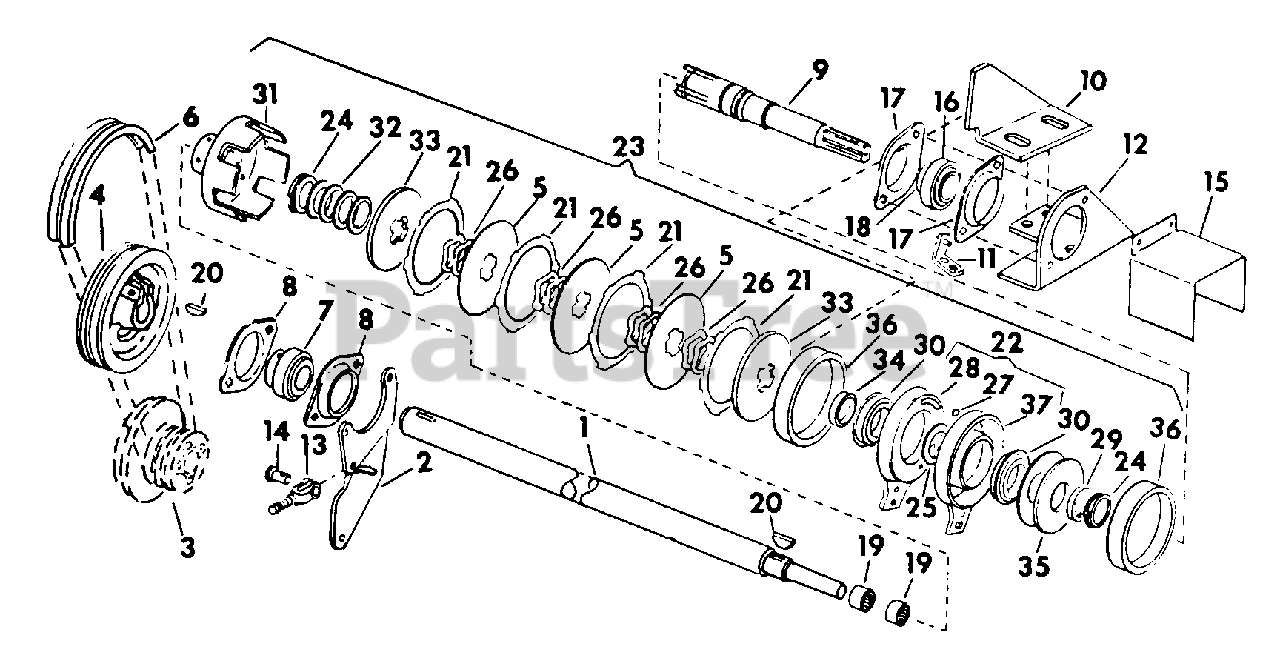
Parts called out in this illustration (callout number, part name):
1	SHAFT, PTO DRIVE
2	ADJUSTER, PTO SHAFT & PULLEY
3	FLYWHEEL AND DRIVE PULLEY
4	PULLEY, PTO DRIVEN
5	DISC SEPARATOR
6	BELTS, MATCHED SET PTO DRIVE V
7	BEARING, PTO SHAFT FRONT BALL
9	SHAFT
10	SUPPORT ASSY, INDEPENDENT PTO BRAKE BRACKET
11	BRACKET, CLUTCH CLEAT
12	SUPPORT, PTO SHAFT BRG MTG BRACKET
13	YOKE ASSY, ADJUSTABLE
14	PIN, 3/8 X 1-3/32 ROD END
15	GUARD, PTO SHAFT
16	BEARING, PTO SHAFT REAR BALL
18	COLLAR W/SET SCREW, LOCKING
19	BEARING, PTO IDLER SHAFT NEEDLE
20	KEY, 3/16 X 1 WOODRUFF 13
21	DISC FRICTION
22	KIT, ACTUATOR REBUILD
23	CLUTCH ASSY, INDEPENDENT PTO
26	SPRING, WAVE
27	BALL, 7/16 CR-STL
28	CAM, ACTUATING
30	BEARING, CAM
31	CUP ASSY, DRIVE
33	PLATE, PRESSURE
35	SPRING, LOAD
37	CAM, STATIONARY
